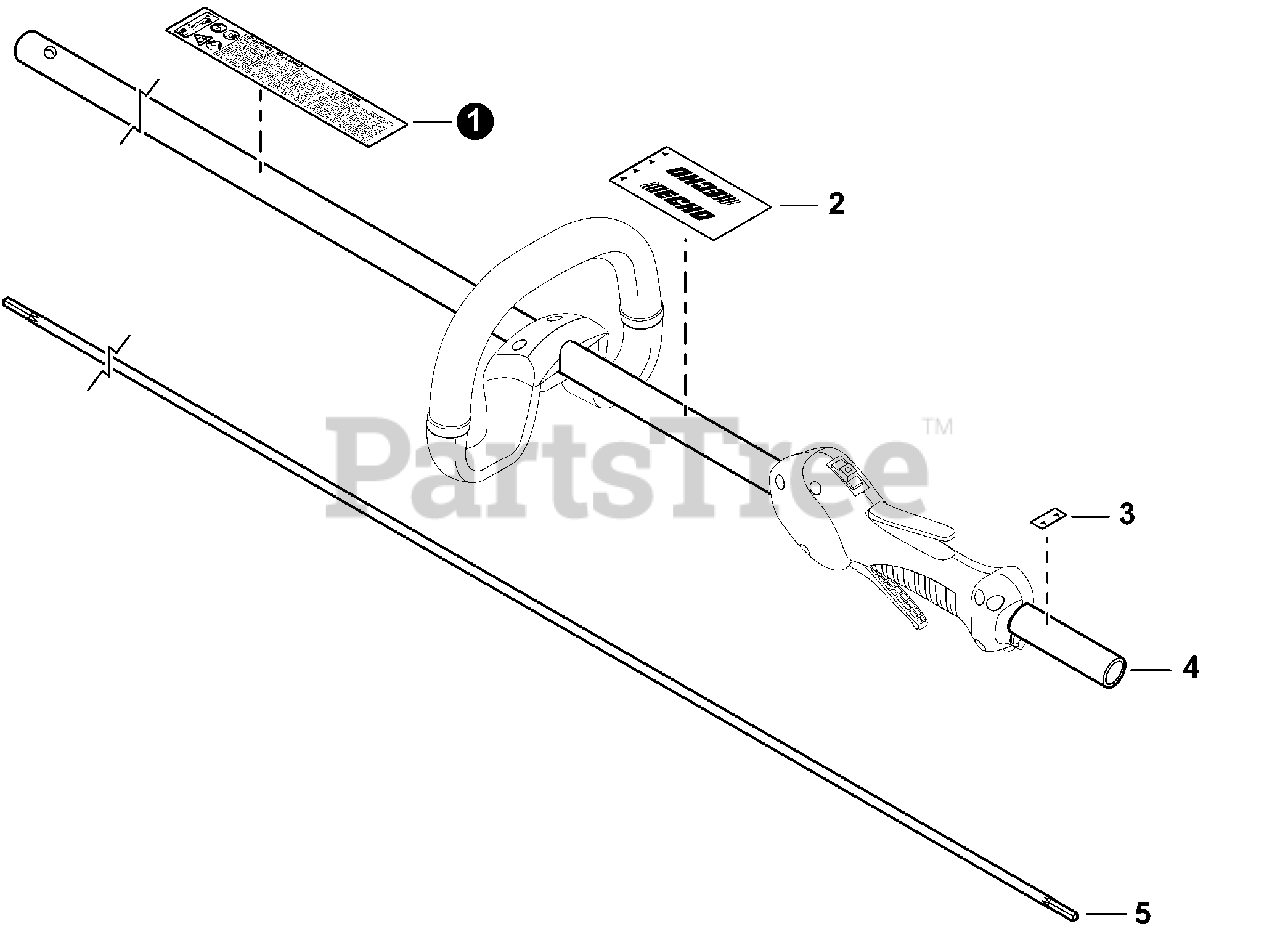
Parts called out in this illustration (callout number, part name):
1	LABEL, CAUTION
2	LABEL, HANDLE LOCATION
3	LABEL - ALIGNMENT
4	MAIN PIPE ASSY
5	DRIVESHAFT
